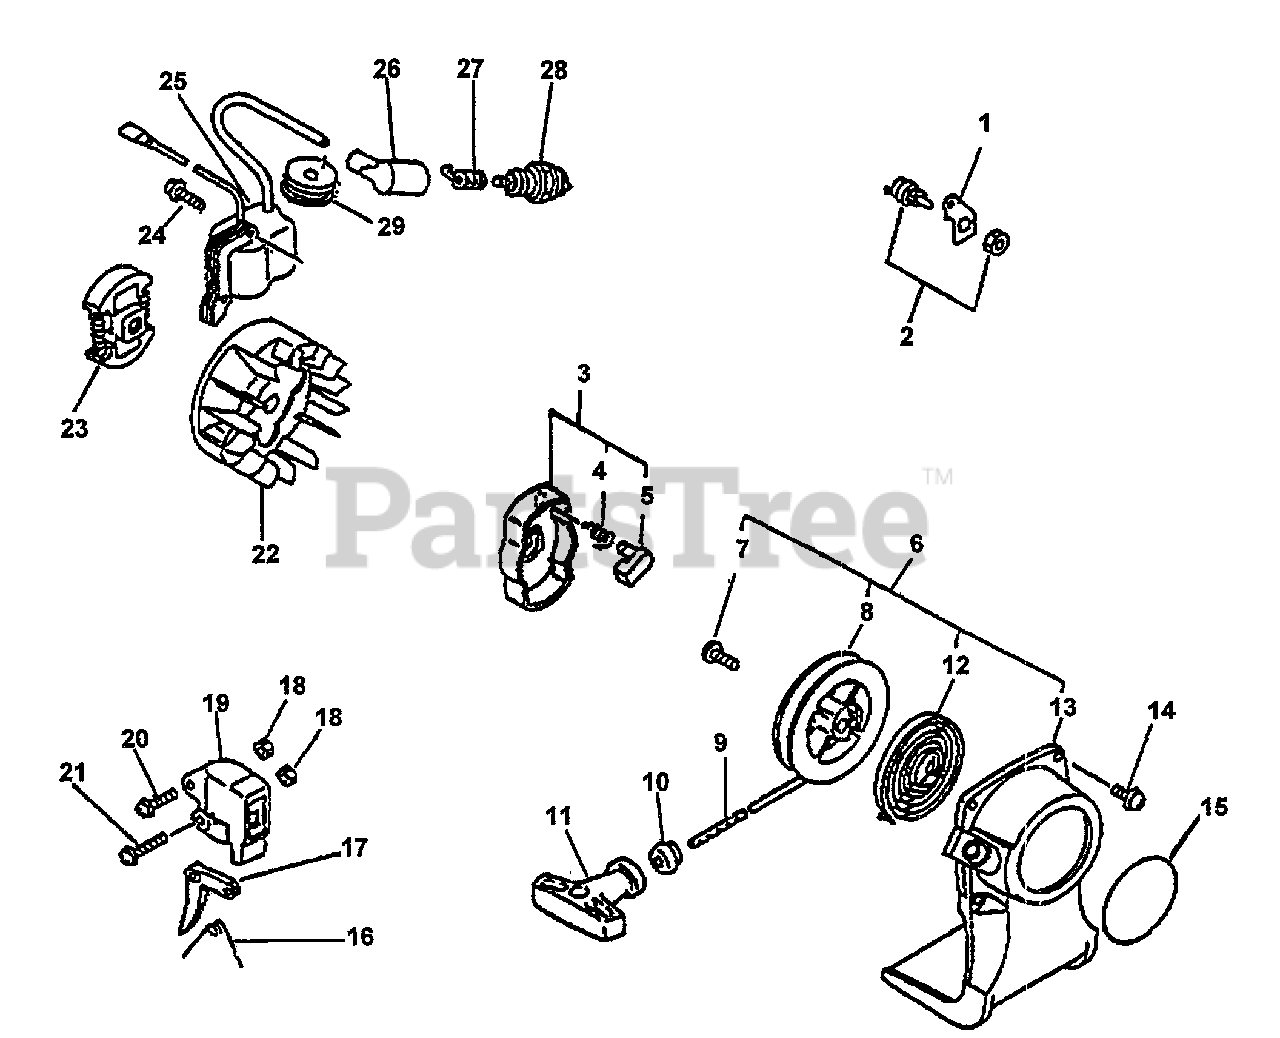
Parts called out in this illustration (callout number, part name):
1	BRACKET, SWITCH
2	IGNITION SWITCH ASSY
3	STARTER PAWL ASSY
4	SPRING, RETURN
5	PAWL, STARTER - BLACK
6	STARTER ASSY
8	REEL, ROPE
9	ROPE, STARTER - 3X890
10	GUIDE, ROPE
11	GRIP, STARTER
12	SPRING, REWIND
13	CASE, STARTER - BLUE
14	SCREW - 4X16
15	LABEL - BRAND
16	SPRING, TRIGGER
17	TRIGGER, THROTTLE
18	LOCKNUT - 5
19	BRACKET, TRIGGER
20	SCREW - 5X30
21	SCREW - 5X28
22	FLYWHEEL
23	CLUTCH ASSY
24	SCREW - 4X22
25	COIL, IGNITION
26	CAP, SPARK PLUG
27	TERMINAL, SPARK PLUG CAP
28	SPARK PLUG -- BPM-7A
29	GROMMET
